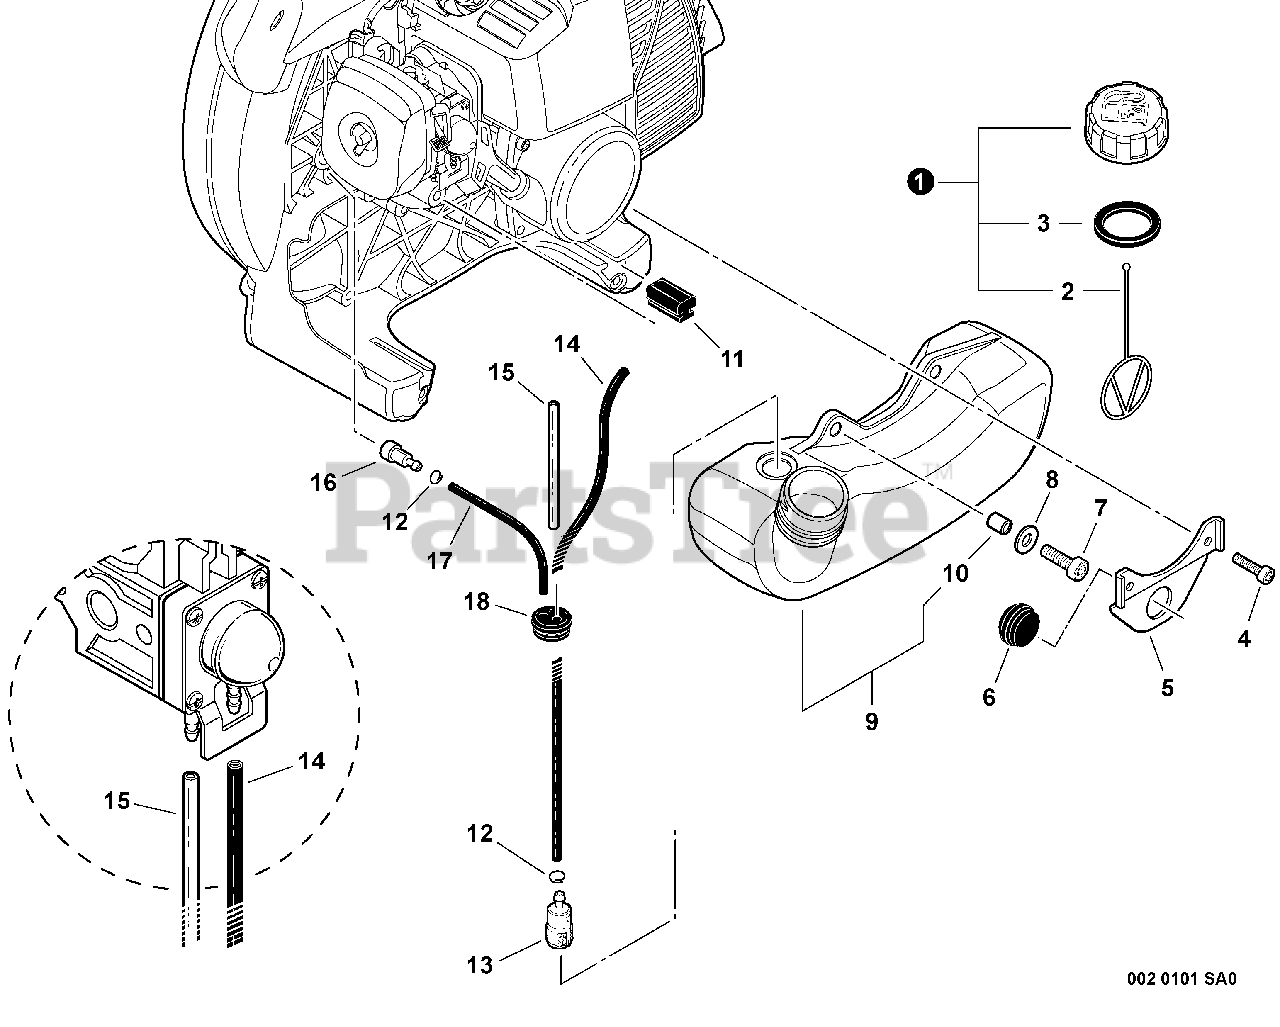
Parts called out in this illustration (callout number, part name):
1	CAP ASSY - ORANGE
2	CONNECTOR, CAP
3	GASKET, CAP
4	SCREW - 4X16
5	BRACKET, FUEL TANK
6	CUSHION
7	SCREW - 5X16
8	WASHER - 5
9	FUEL TANK ASSY
12	CLIP - 6
13	FILTER, FUEL
14	PIPE - 3X5X210 -- BLACK
15	PIPE - 3X6X85 -- CLEAR
16	VENT, FUEL TANK
17	PIPE - 3X6X80 -- BLACK
18	GROMMET
